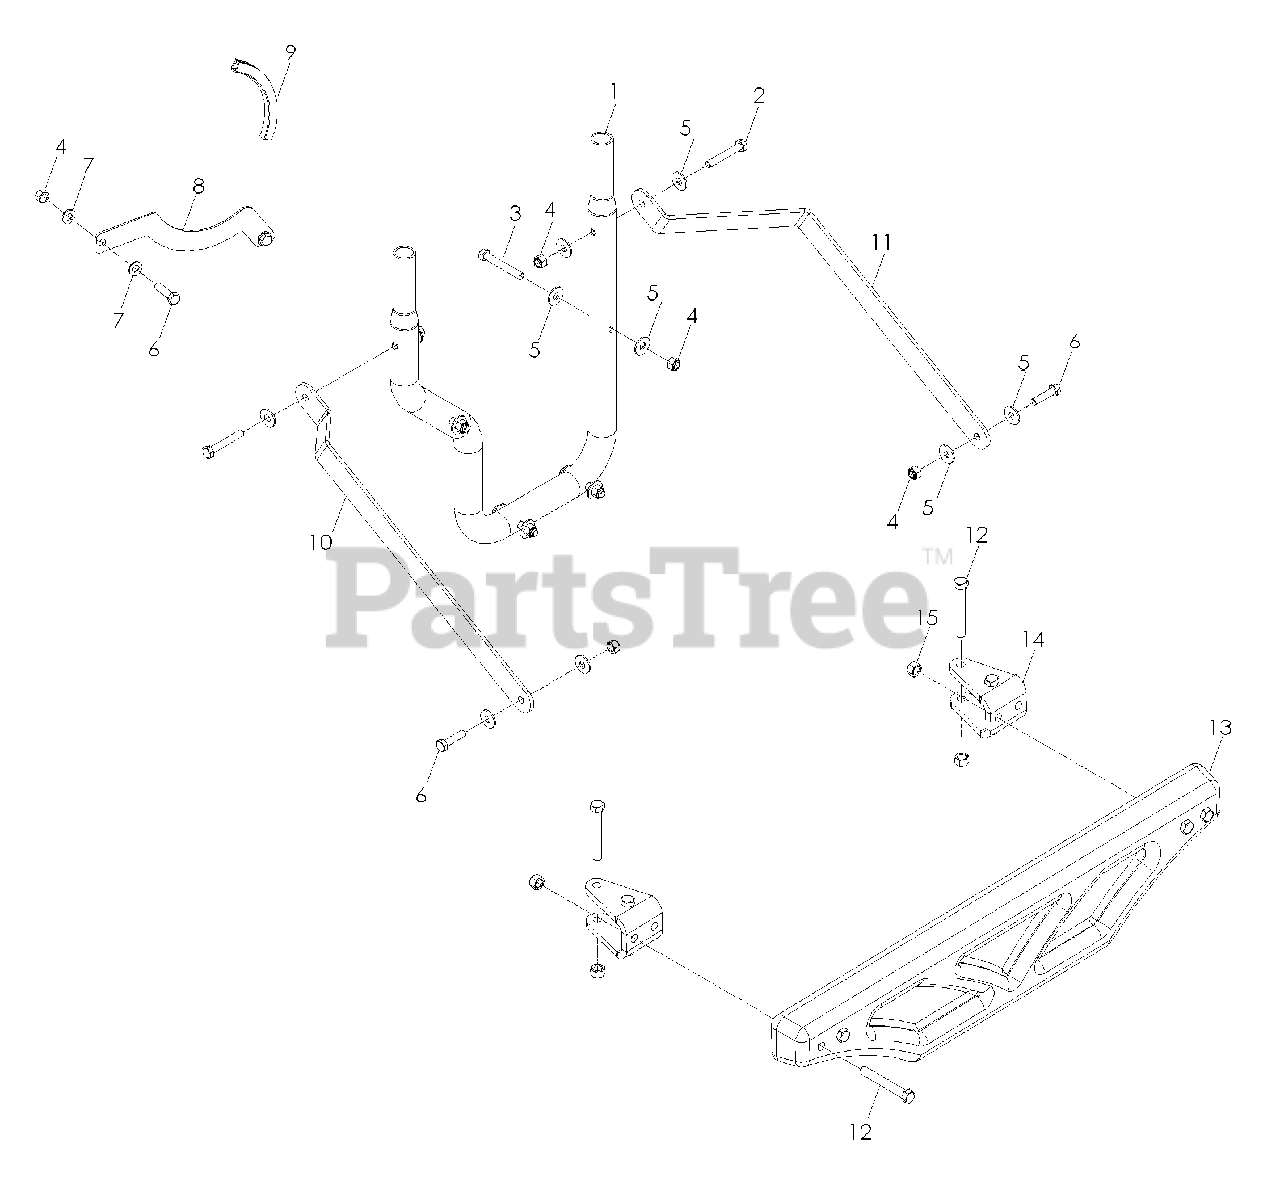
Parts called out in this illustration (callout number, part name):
1	TUBE, MOUNT
2	HCS 5/16-18 x 2
3	HCS 5/16-18 x 2 1/4
4	NUT 5/16-18 HEx NYLOC
5	WASHER 5/16 STD FLT
6	HCS 5/16-18 x 1 1/4
7	WASHER 5/16 SAE FLT
8	SUPPORT, CHUTE
9	FLEx TRIM
12	HCS 3/8-16 x 2 3/4
13	CAST WEIGHT
14	BRACKET, WEIGHT
15	NUT 3/8-16 HEx NYLOC
